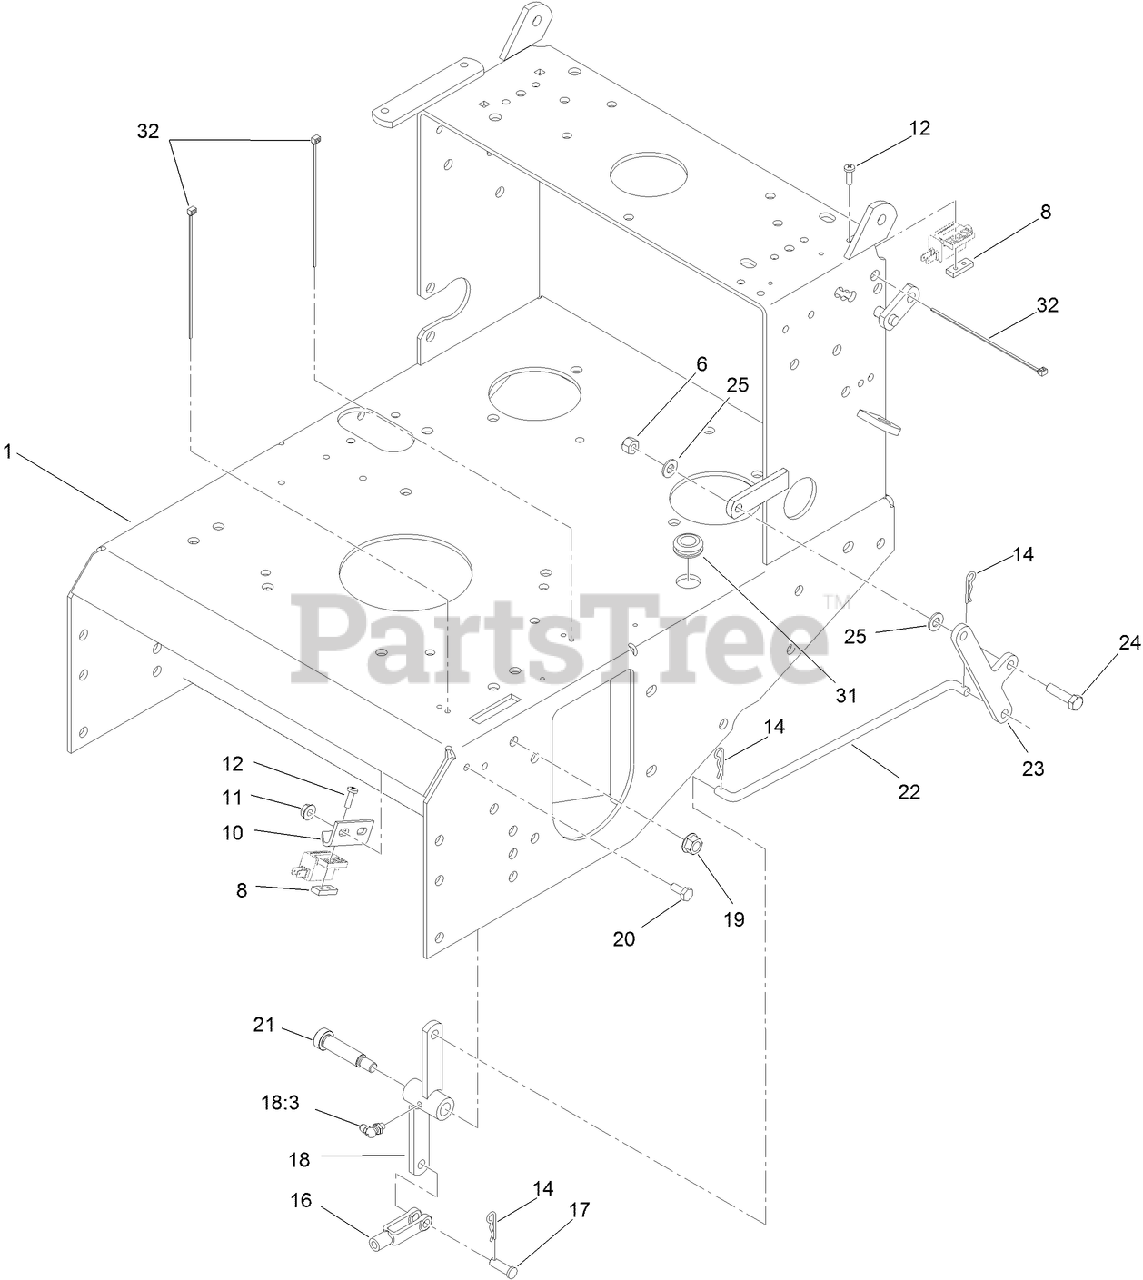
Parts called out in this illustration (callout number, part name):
6	NUT-LOCK, NI
8	PLATE-TAPPED
10	BRACKET-SWITCH, BLADE
11	NUT-HF
12	SCREW-PPH
14	PIN-COTTER
16	YOKE-ADJUSTABLE
17	PIN-CLEVIS
18	BELLCRANK ASM
18:3	FITTING-GREASE, 90 DEG
19	NUT-HF
20	SCREW-HH
22	LINKAGE-ENGAGE, BLADE
23	BELLCRANK
24	SCREW-HH
25	WASHER-PLAIN
31	GROMMET
32	TIE-CABLE
